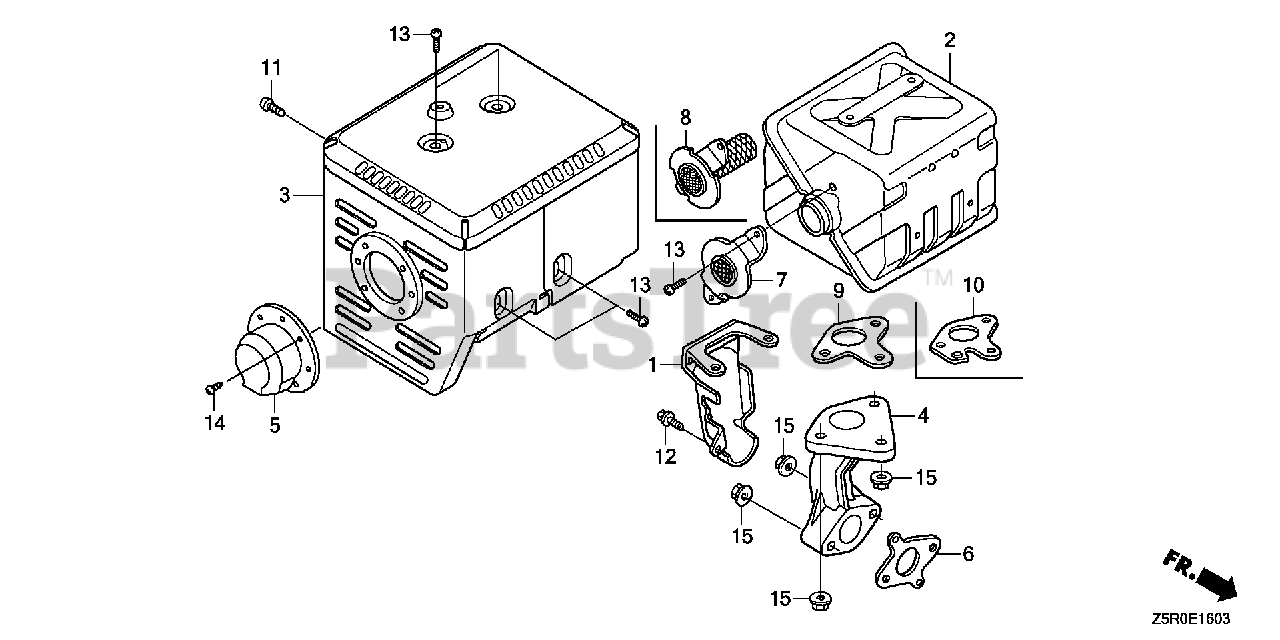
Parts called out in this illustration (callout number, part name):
2	MUFFLER
3	PROTECTOR, MUFFLER
6	GASKET, EX. PIPE
7	FLANGE, BAFFLE
8	ARRESTER, SPARK
9	GASKET, MUFFLER (NIPPON LEAKLESS)
10	GASKET, MUFFLER (ARRESTER) (NIPPON LEAKLESS)
11	SCREW, TAPPING (6X10)
13	SCREW, TAPPING (5X8)
15	NUT, FLANGE (8MM)
